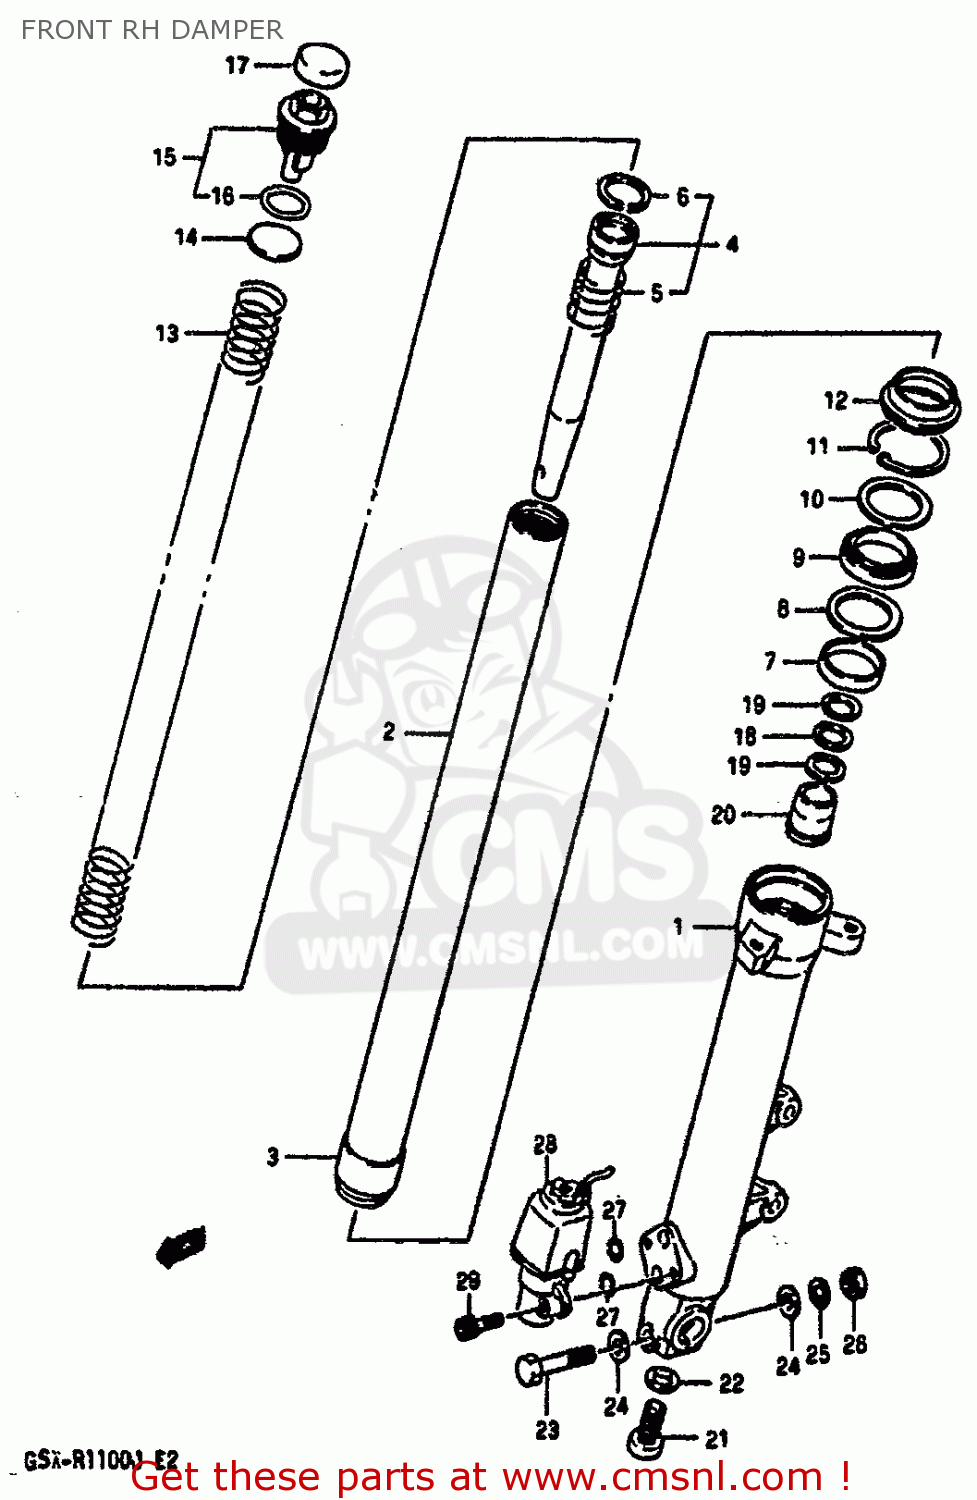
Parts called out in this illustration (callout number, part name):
1	TUBE,OUTER,RIGHT
2	TUBE,INNER
3	METAL,SLIDE FR FORK
4	CYLINDER
5	SPRING,REBOUND
6	RING,FR FORK PISTON
7	METAL,SLIDE
8	WASHER,FORK OIL SEAL
9	OIL SEAL,FRONT FORK
10	WASHER,FORK OIL SEAL
11	RING,OIL SEAL STOPPER
12	DUST SEAL,FRONT FORK
13	SPRING
14	WASHER,FR FORK SPRING
15	CAP,FORK INNER TUBE
16	O RING
17	CAP,FORK INNER TUBE
18	WASHER,OIL LOCK PIECE
19	SPRING,FORK OIL LOCK PIECE
20	PIECE,OIL LOCK
21	BOLT(14X25)
22	GASKET (NAS)
23	BOLT 10X60
24	WASHER
25	EAND ASSY
26	NUT
27	O RING
29	BOLT
